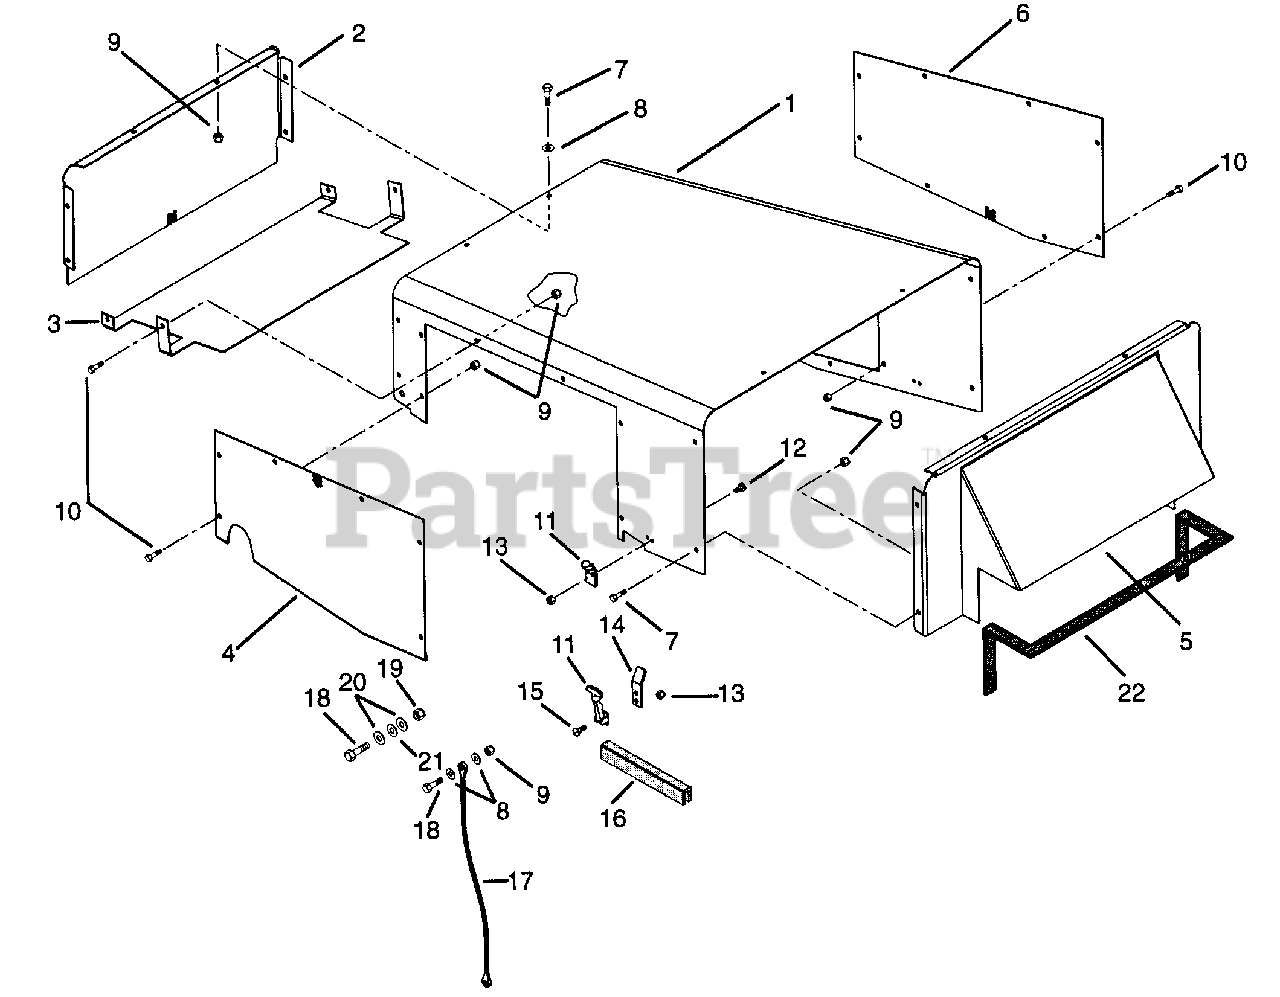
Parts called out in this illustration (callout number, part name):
1	Hood, PM-350
2	Screen,Hood
3	Shield,Exhaust Cover
4	Screen,Kawasaki Right Hand
5	Weldment,Hood Intake Shield
7	Bolt-Hex .25-20 x .63
8	Washer-Flat-Steel .281 x .625 x .065
9	Nut-Locking-Nylon .250-20 Grade 2
10	Screw-Machine .25-20
11	Latch
12	Screw-Machine 10-24 x .50
13	Nut-Locking 10-24
14	Plate,Guide
15	Screw-Machine 10-24 x .750
16	Strip,Cowl
17	Cable,Hood Plated
18	Bolt-Hex .380-16 x .875
19	Nut-Locking-Nylon .375-16 Grade 2
20	Washer-Flat-Steel .406 x .812 x .065
21	Washer-Flat-Nylon .375 x .75 x .060
22	Seal,Trim-Lok Bulk
